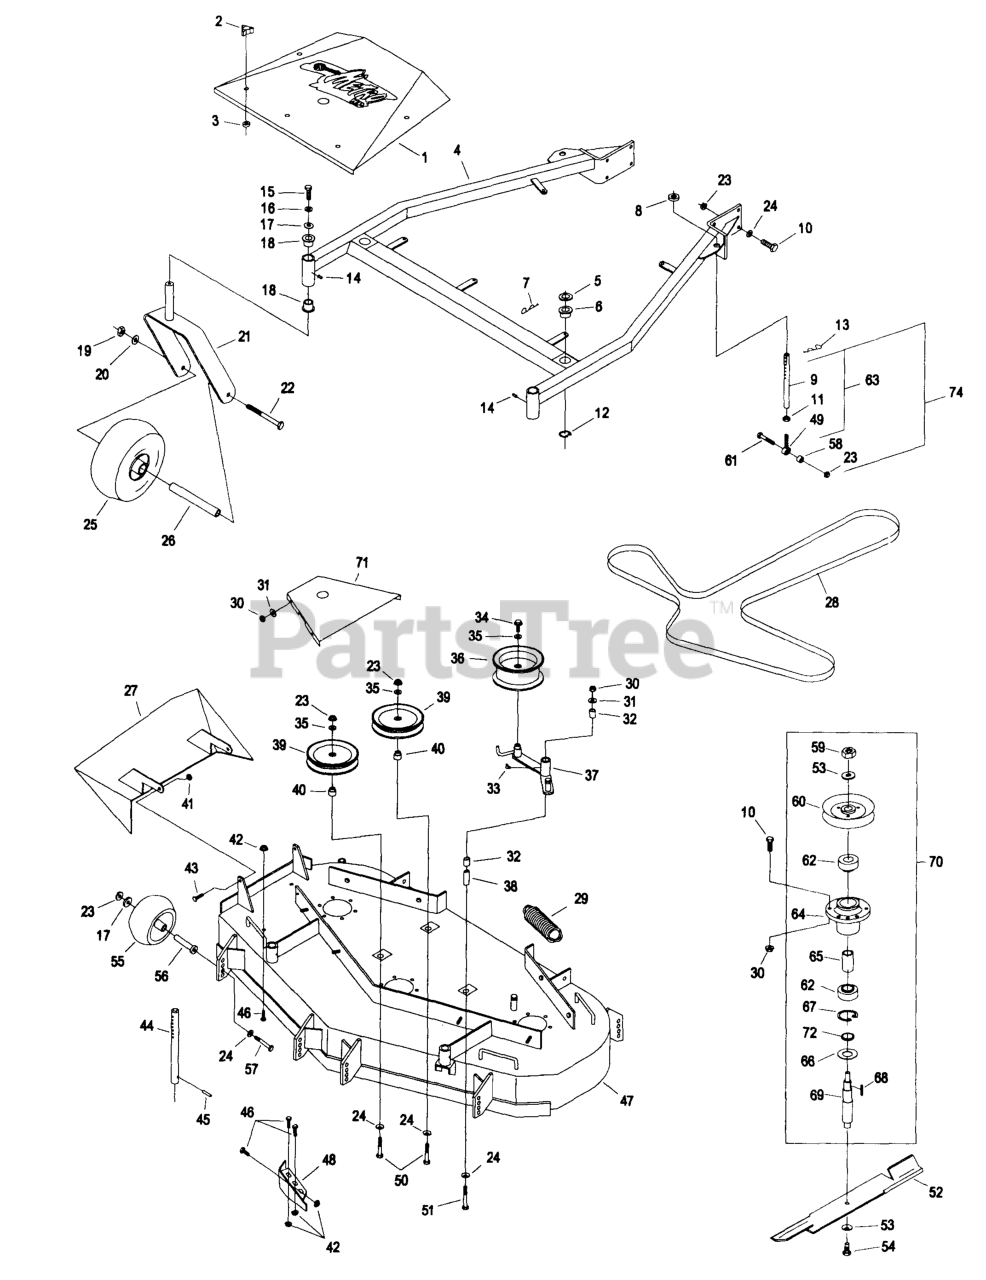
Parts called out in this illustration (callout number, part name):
1	SHIELD W/DECAL,MHP52
2	KNOB-3 PRONG
4	SUPPORT,DECK W/BUSHINGS
5	SPACER-DECK SUPPORT
6	BUSHING-DECK
9	LINK, DECK SUPPORT
13	PIN,HAIR COTTER
18	BEARING-FLANGED
27	WLD,CHUTE DISCHARGE
28	BELT,DECK DRIVE
32	SLEEVE-BEARING
38	BUSHING-PIVOT, IDLER
39	PULLEY-IDLER
40	BUSHING-IDLER
44	ROD,DECK SUPPORT
47	ASM,DECK W/DECALS TTHP52
48	WLD,BAFFLE DISCHARGE
49	BALLJOINT
51	SCREW-HH
53	WASHER-SPRING
55	ROLLER-SCALP, ANTI
56	BUSHING-ROLLER
60	SHEAVE,W/HUB 5.72
62	BEARING
65	SPACER-BEARING
66	GUARD-BEARING, BOTTOM
68	KEY-RECTANGLE
69	SHAFT,SPINDLE
70	HOUSING,CUTTER COMPLETE
72	SPACER-PULLEY/BEARING
